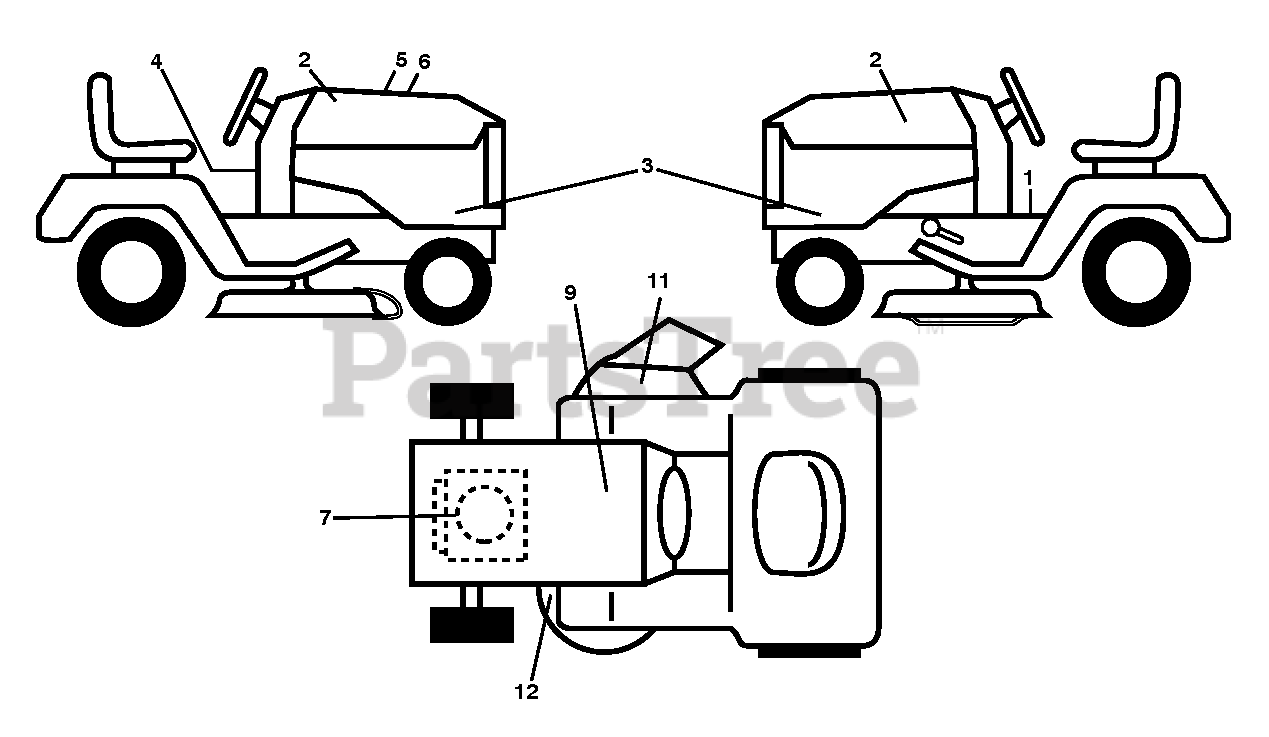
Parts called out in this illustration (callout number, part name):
1	DECAL.WARN.STARTINST.LOWEARIEN
2	DECAL.BADGE.170MM.TEXTLOGO.
3	DECAL TRACTOR SIDE PANEL SDPNL
4	DECAL, WARNING SPARK ARRESTOR
5	DECAL.WARNING.CUST.RESP.E85.
6	DECAL.RPL.BSM44.INTK.TLW.46.GE
7	DECAL.ENG.BS.22INTK.DOM.381708
9	DECAL BTRY SYMBOLS
11	DECAL, DECK DEFLECTOR, WARNING
12	DECAL.V-BELT.SCH.42/46"MEC/ELE
